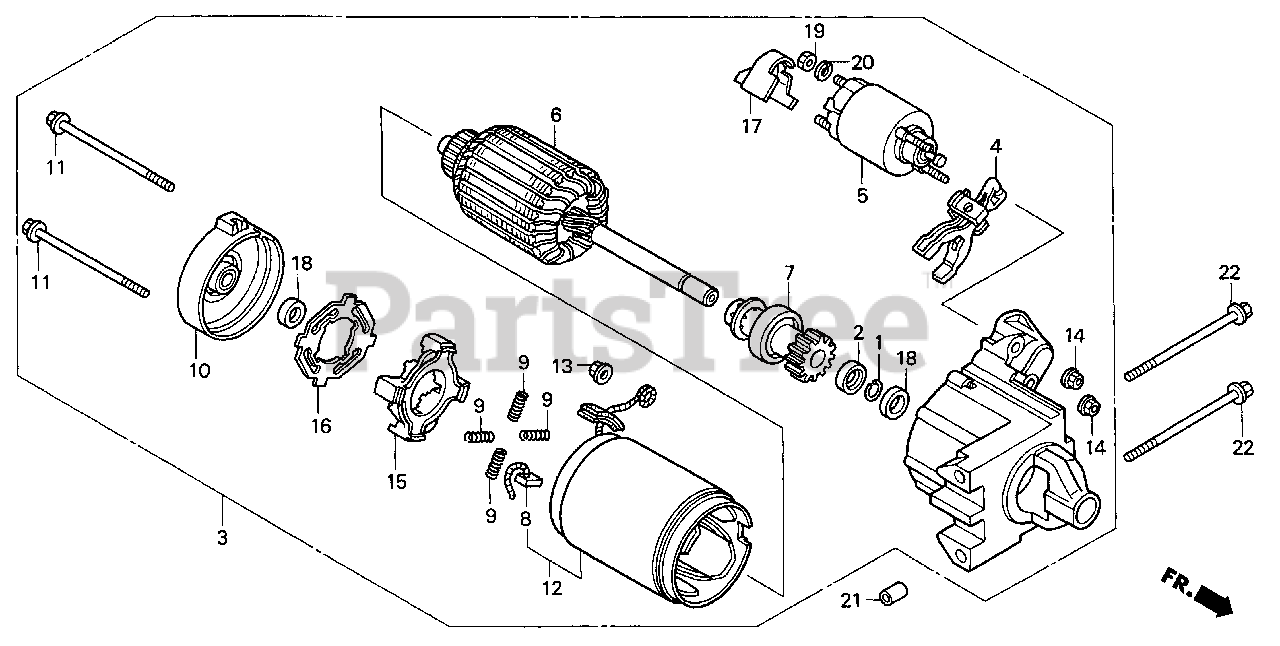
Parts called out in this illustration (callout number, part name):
1	RING, SNAP (DENSO)
2	COLLAR SET, CLUTCH STOP
3	MOTOR ASSY., STARTER
4	LEVER, PINION DRIVE
5	SWITCH ASSY., MAGNET
6	ARMATURE COMP.
7	CLUTCH COMP., OVERRUNNING
8	BRUSH
9	SPRING, BRUSH
10	COVER
11	BOLT, THROUGH
12	YOKE COMP.
13	NUT, HEX. (8MM)
14	NUT, FLANGE (5MM)
15	HOLDER, BRUSH
16	INSULATOR, BRUSH HOLDER
17	COVER, TERMINAL
18	BEARING A
19	NUT, HEX. (8MM)
20	WASHER, SPRING (8MM)
21	PIN, DOWEL (10X12)
22	BOLT, FLANGE (8X110)
